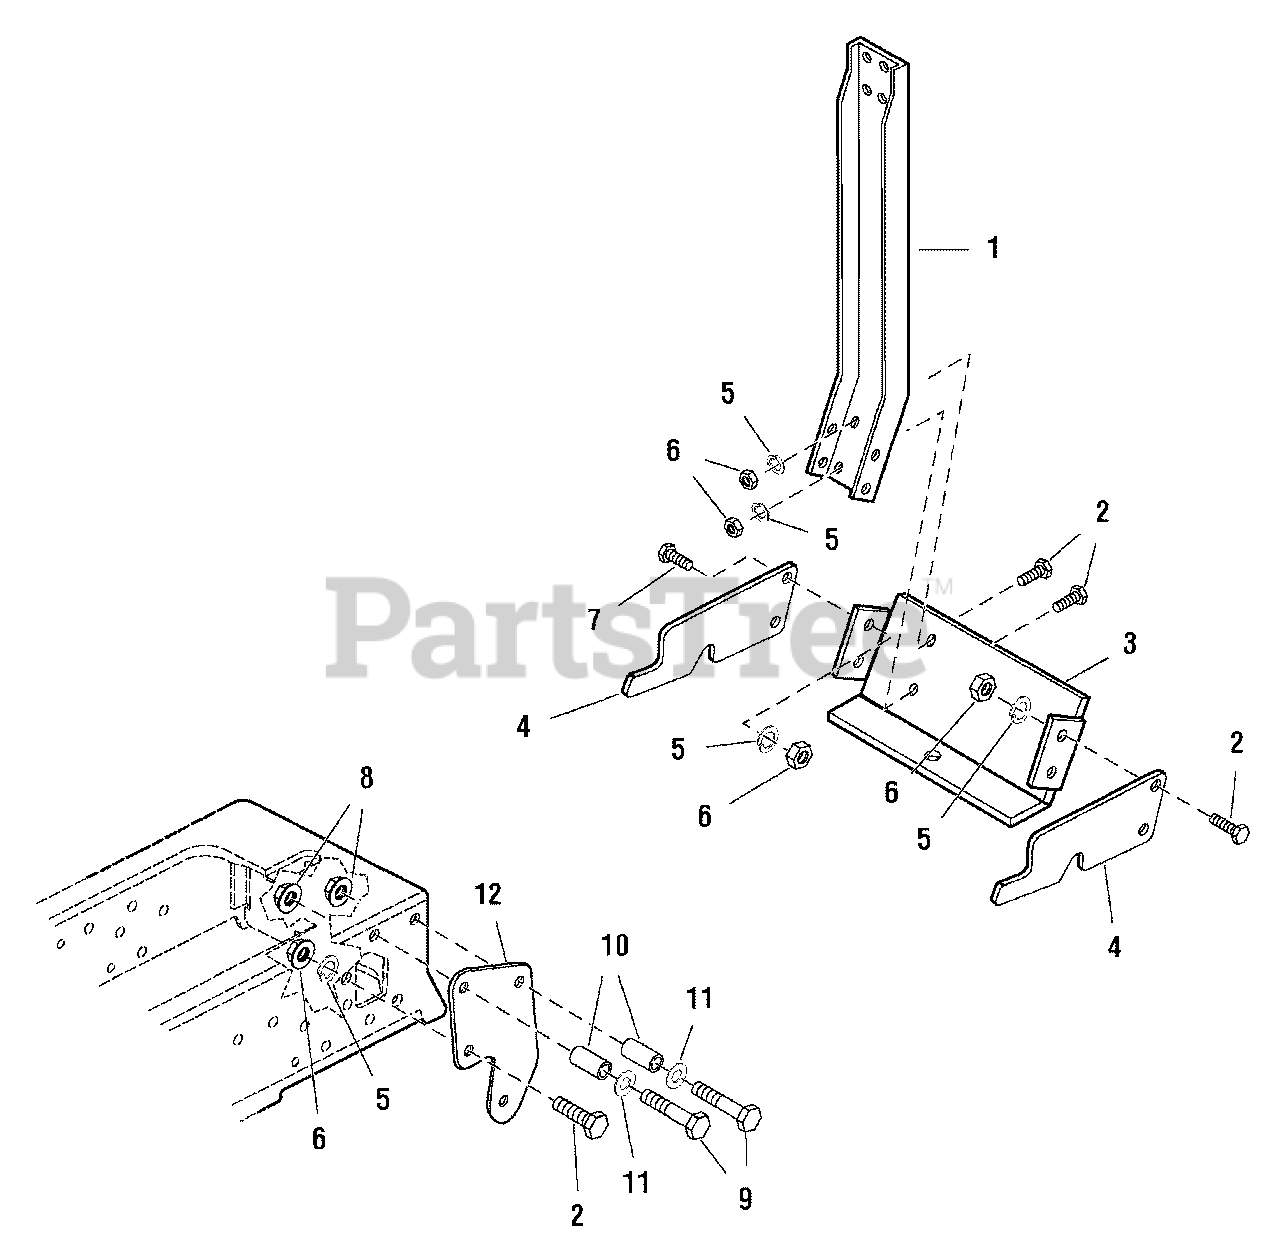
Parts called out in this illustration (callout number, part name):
1	SUPPORT, Upright
2	CAPSCREW, Hex Head, 3/8-16 x 1
3	BRACKET, Lower Hitch
4	SUPPORT, Side Hitch
5	LOCKWASHER, 3/8
6	NUT, Hex, 3/8-16
7	CAPSCREW, Hex Head, 3/8-16 x 1-1/4
8	LOCKNUT, Hex, 1/2-13
9	CAPSCREW, Hex Head, 1/2-13 x 2-1/2
11	WASHER
